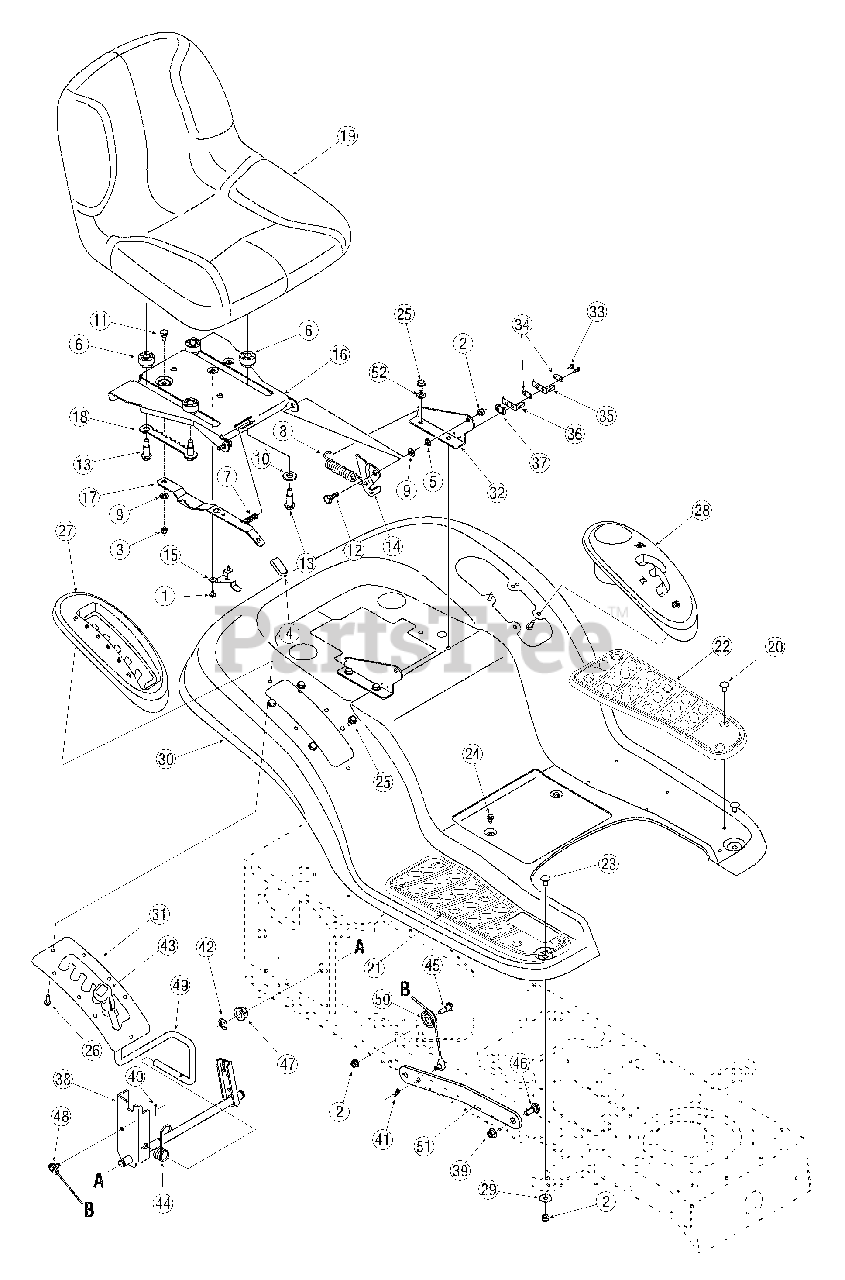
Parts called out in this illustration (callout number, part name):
1	Screw, #10-16 x.375
2	Nut, Flange Lock, 5/16-18, Gr F, Nylon
3	Nut, Flange Lock, 1/4-20
4	Seat Adjuster Grip
5	Nut, Speed,.3125 ID
6	Spacer
7	Compression Spring,.41 x 1.5
8	Spring, Extension,.84 Dia. x 4.6
9	Wash, Flat,.344 x.688 x.065
10	Wash, Flat,.531x 1.062 x.134
11	Screw, Shoulder,.340 x.285,1/4-20
12	Screw, Shoulder,.437 x.268, 5/16-18
13	Screw, Shoulder,.50 x.925, 3/8-16
14	Seat Bracket, Lift
15	Seat Stop
18	Seat Adjustment Selector
19	High Back Seat, Black
20	Ratchet Clip
21	RH Foot Pad, Rubber
22	LH Foot Pad, Rubber
23	Bolt, Carriage, 5/16-18,.62, Gr1
24	Screw, 1/4-20, 0.500
25	Screw, 5/16-12, 0.750
26	Screw, 1/4-15, 0.750
27	Cover, Lift Lever
28	Cover, w/ Cup Holder
29	Washer, Flat,.344 x 1.0 x.063
33	Screw, #8-18 x.50
34	Plate, Insulator
35	Spring Switch, Outer
36	Spring Switch, Inner
37	Plate, Insulator Boss
39	Nut, Flange Lock, 3/8-16, Gr F, Nylon
40	Pin, Cotter,.072 Dia. x 1.13
41	Pin, Cotter, 3/32, 1.0
42	Ring, E Type,.625 Dia.
43	Grip, Handle, 1/2
44	Spring, Torsion
45	Screw, 5/16-18 x.620 Gr2
46	Screw, Shoulder,.625 x.165, 3/8-16
47	Bearing, Hex Flange
48	Cable, Lift, 16.16
49	Handle, Lift
50	Pulley, Roller
52	Lock Washer, 5/16
